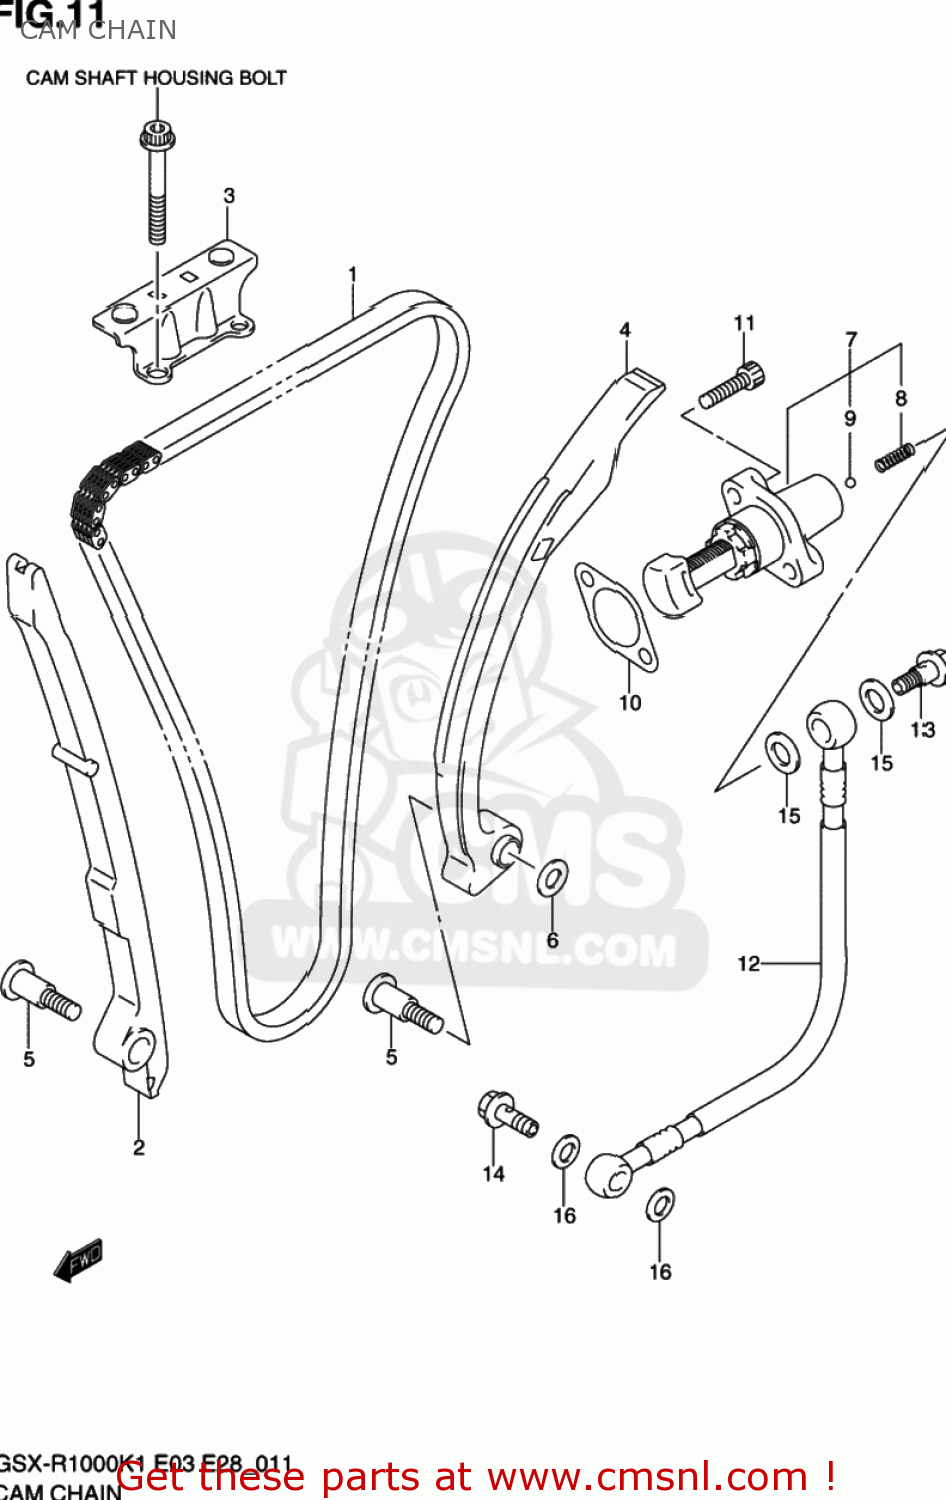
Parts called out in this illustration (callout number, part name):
1	CHAIN COMP,CAM
2	GUIDE,CAM CHAI
3	GUIDE CAM CHAIN NO,2
4	TENSIONER,CAM CHAIN
5	BOLT,CAM CHAIN TENSIONER/GUIDE
6	WASHER
7	ADJUSTER ASSY,TENSIONER
8	SPRING
9	BALL
10	GASKET,TENSIONER ADJUSTER (NAS)
11	BOLT,CL.COVER
12	HOSE,TENSIONER ADJUSTER OIL
13	BOLT, OIL HOSE UNION NO.1
14	BOLT,ADJUST OIL HOSE UNION
15	GASKET(12X17X1) (NAS)
16	GASKET 8.2X14X1 (NAS)
